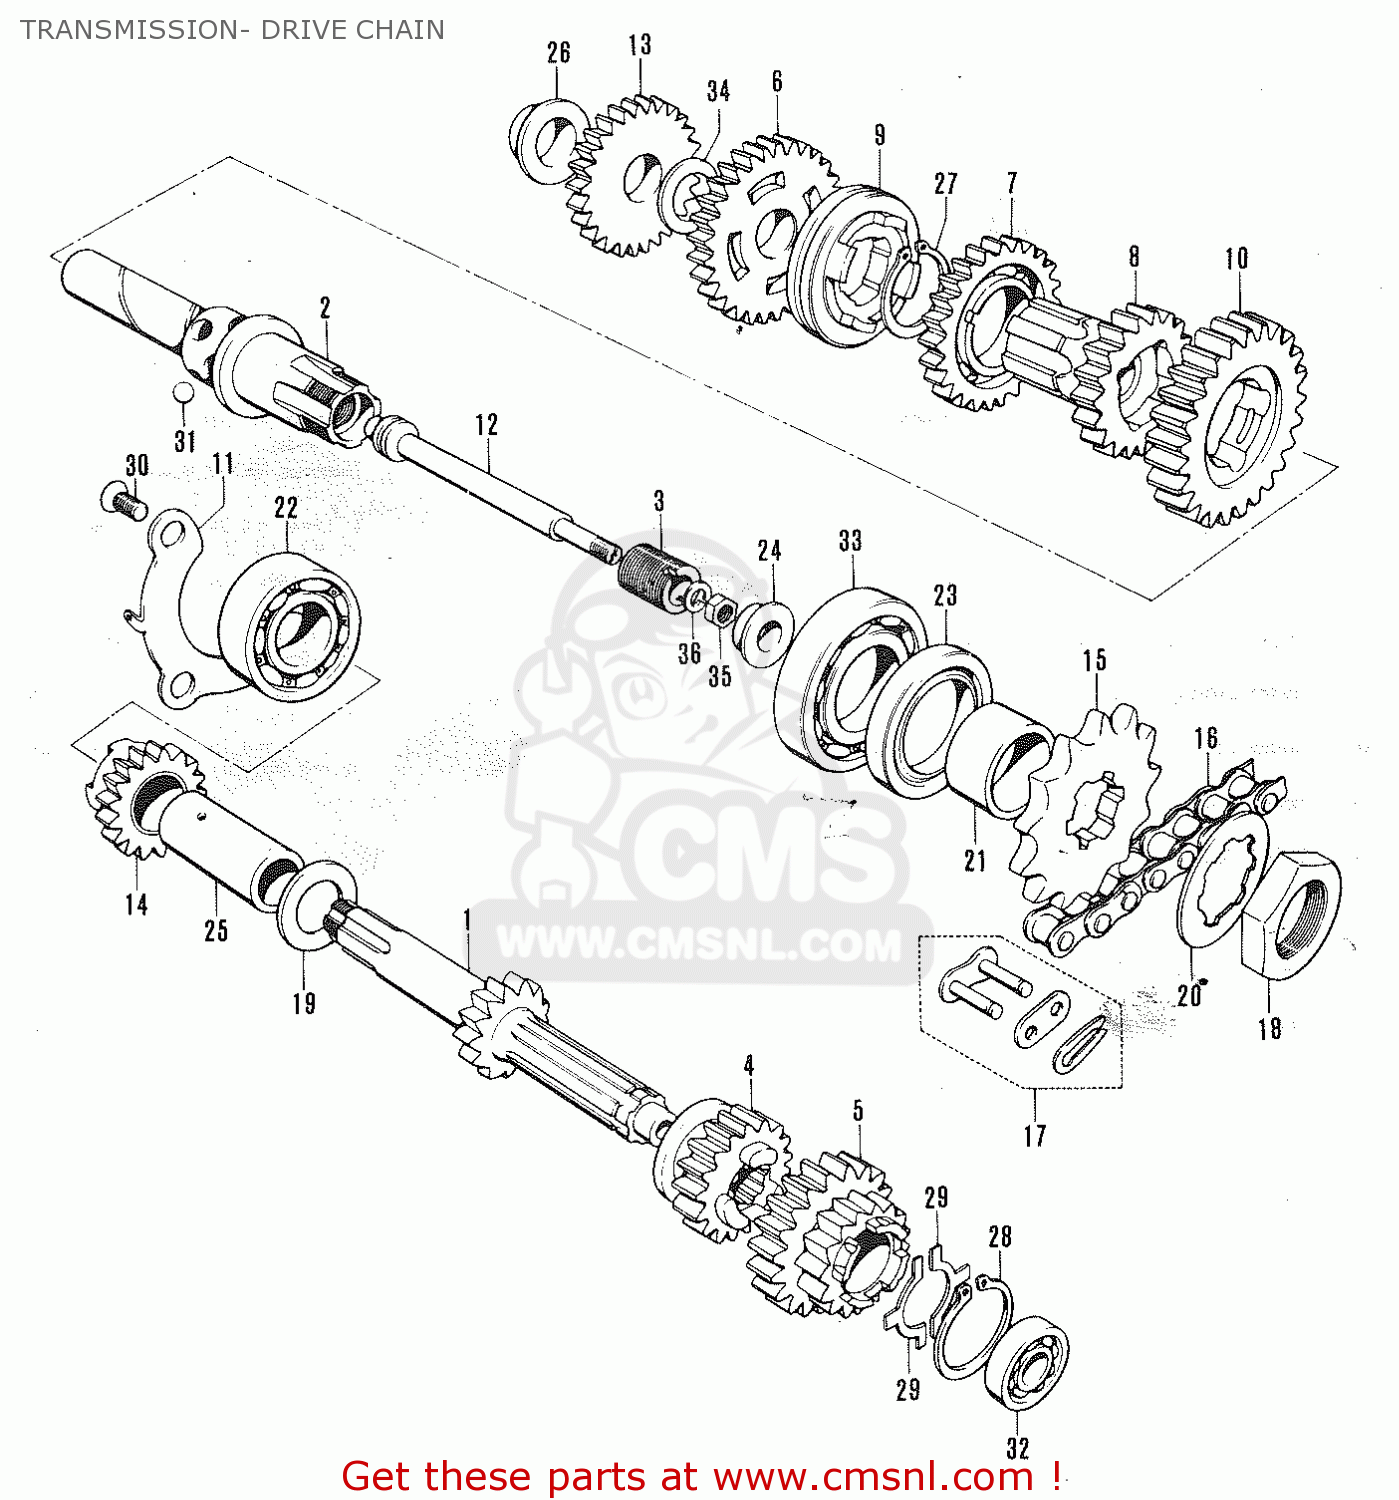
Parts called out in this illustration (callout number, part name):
1	SHAFT,COUNTER
2	SHAFT,DRIVE
3	SPACER
4	GEAR,SECOND DRIVE
5	GEAR,THIRD DRIVE
6	GEAR,FIRST DRIVEN
7	GEAR,SECOND DRIVEN
8	GEAR,THIRD DRIVEN
9	FIRST DRIVEN GEAR WHEEL
10	REDUCTION GEAR
11	PLATE,COUNTERSHAFT BEARING
12	REDUCTION SHIFTING ROD
13	GEAR,KICK STARTER IDLE
14	GEAR,KICK STARTER DRIVEN
15	SPROCKET,ENGINE
16	CHAIN ASSEMBLY,DRIVE
17	JOINT ASSEMBLY,CHAIN
18	NUT
19	WASHER
20	WASHER
21	SPACER
22	BEARING
23	SEAL,OIL(30X44X6)
24	OIL SEAL
25	BUSHING
26	BUSHING
27	RING,SNAP
28	RING,SNAP
29	RING
30	SCREW
31	BALL
32	BALL BEARING
33	BEARING
34	WASHER,THRUST
35	NUT
36	LOCK WASHER
